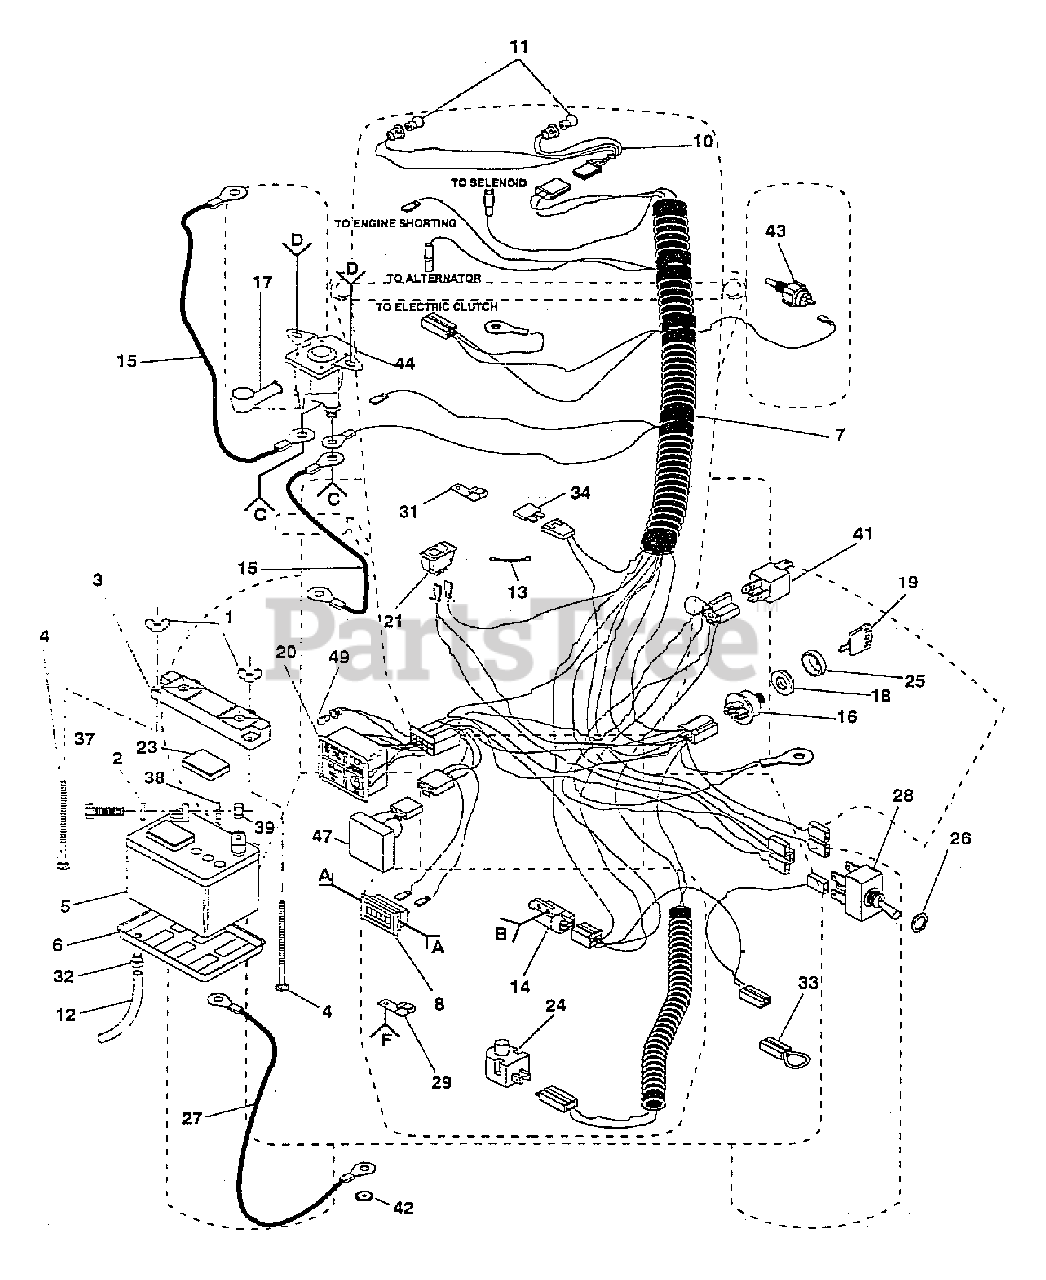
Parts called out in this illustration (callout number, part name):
1	Nut, Wing 1/4-20
2	Washer 9/32 x 518 x 16 Gauge
3	Guard, Terminal
4	Bolt, Carriage 1/4-20 x 7-1/2
5	Battery
6	Tray, Battery
7	Harness, Ignition
8	Meter, Hour
10	Harness, Light Socket
11	Bulb, Light
12	Tube, Battery Tray
13	Tie, Cable
14	Switch, Interlock (Clutch)
15	Cable, Battery (2)
16	Switch, Ignition
17	Cover, Terminal
18	Nut, Ignition
19	Key, Molded
20	Light, Package
21	Switch, Light
23	Caps, Battery
24	Switch, Plunger
25	Bezel, Ignition
26	Nut, Hex
27	Cable, Battery
28	Switch, PTO
29	Clip, Insulated
31	Clip, Fuel Line
32	Clamp, Hose
33	Loop, Wire
37	Bolt, Hex 1/4-20 x 3/4
38	Washer, Lock 1/4
39	Nut, Hex 1/4-20
42	Washer, Lock, External Tooth 3/8
43	Switch, Oil Sensor
44	Solenoid
47	Sensor, Low Voltage
49	Bulb, Light Package
